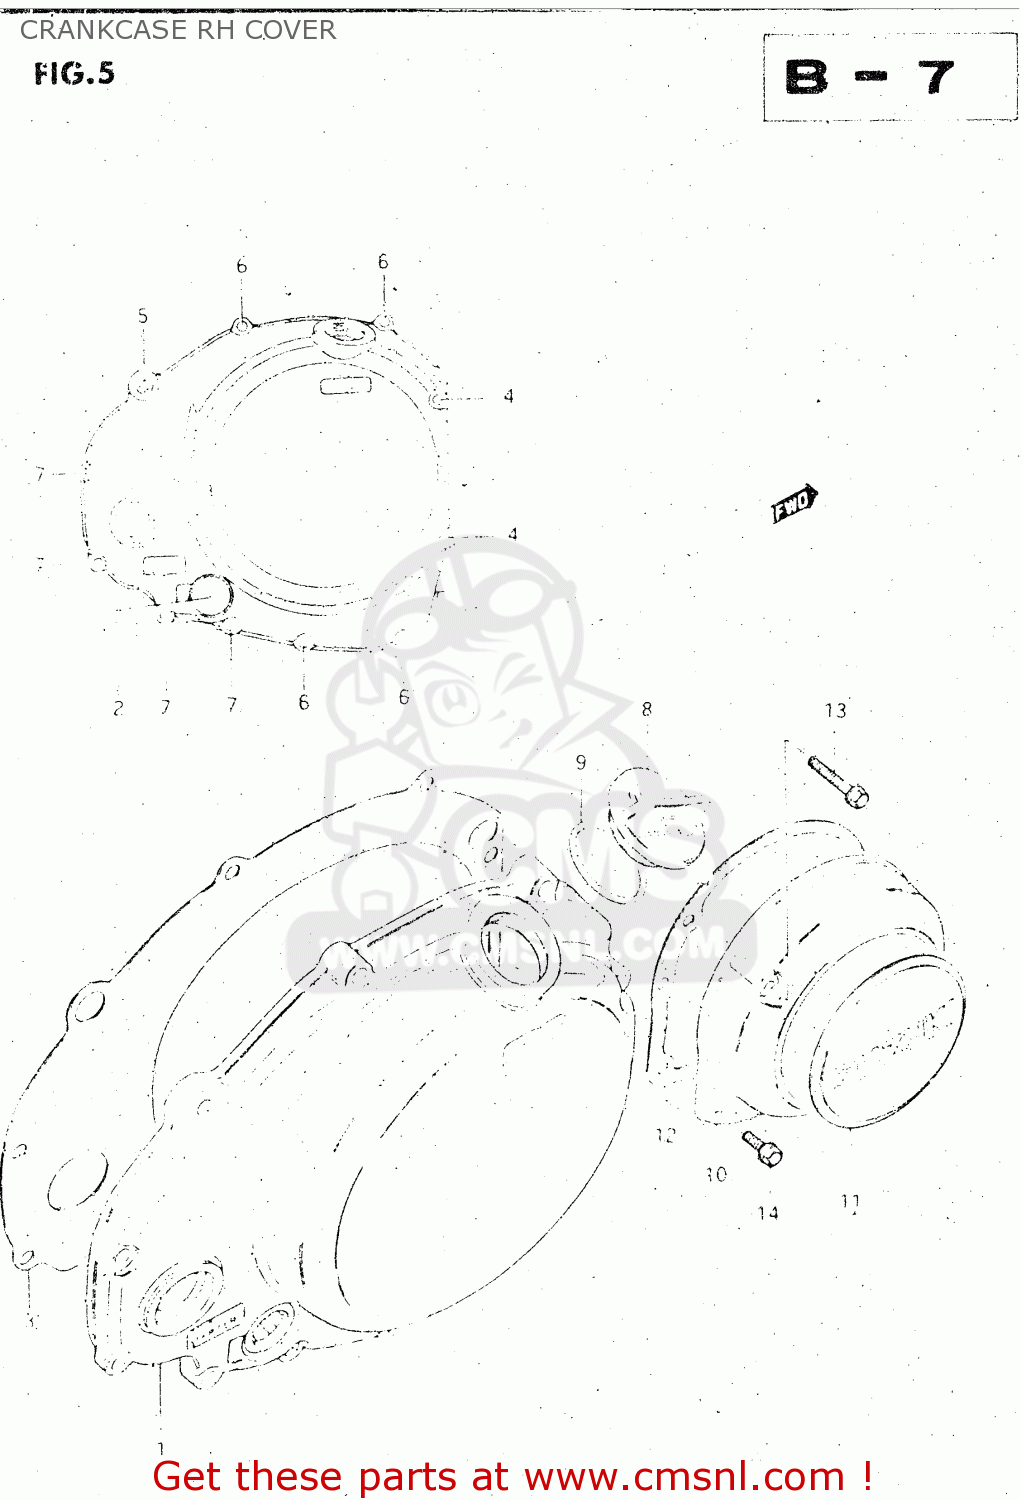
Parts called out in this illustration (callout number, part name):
1	COVER,CLUTCH
2	LENS,OIL LEVEL CHECK
3	GASKET,CLUTCH COVER (MCA)
4	BOLT (6X40)
5	BOLT (6X35)
6	BOLT
7	BOLT (6X20)
8	CAP
9	O RING(D:2.2,ID:32)
10	COVER,CONTACT BREAKER
11	EMBLEM,CONTACT BREAKER COVER
12	GASKET,CONTACT BREAKER COVER (NAS)
13	BOLT (5X30)
14	BOLT 5X16
